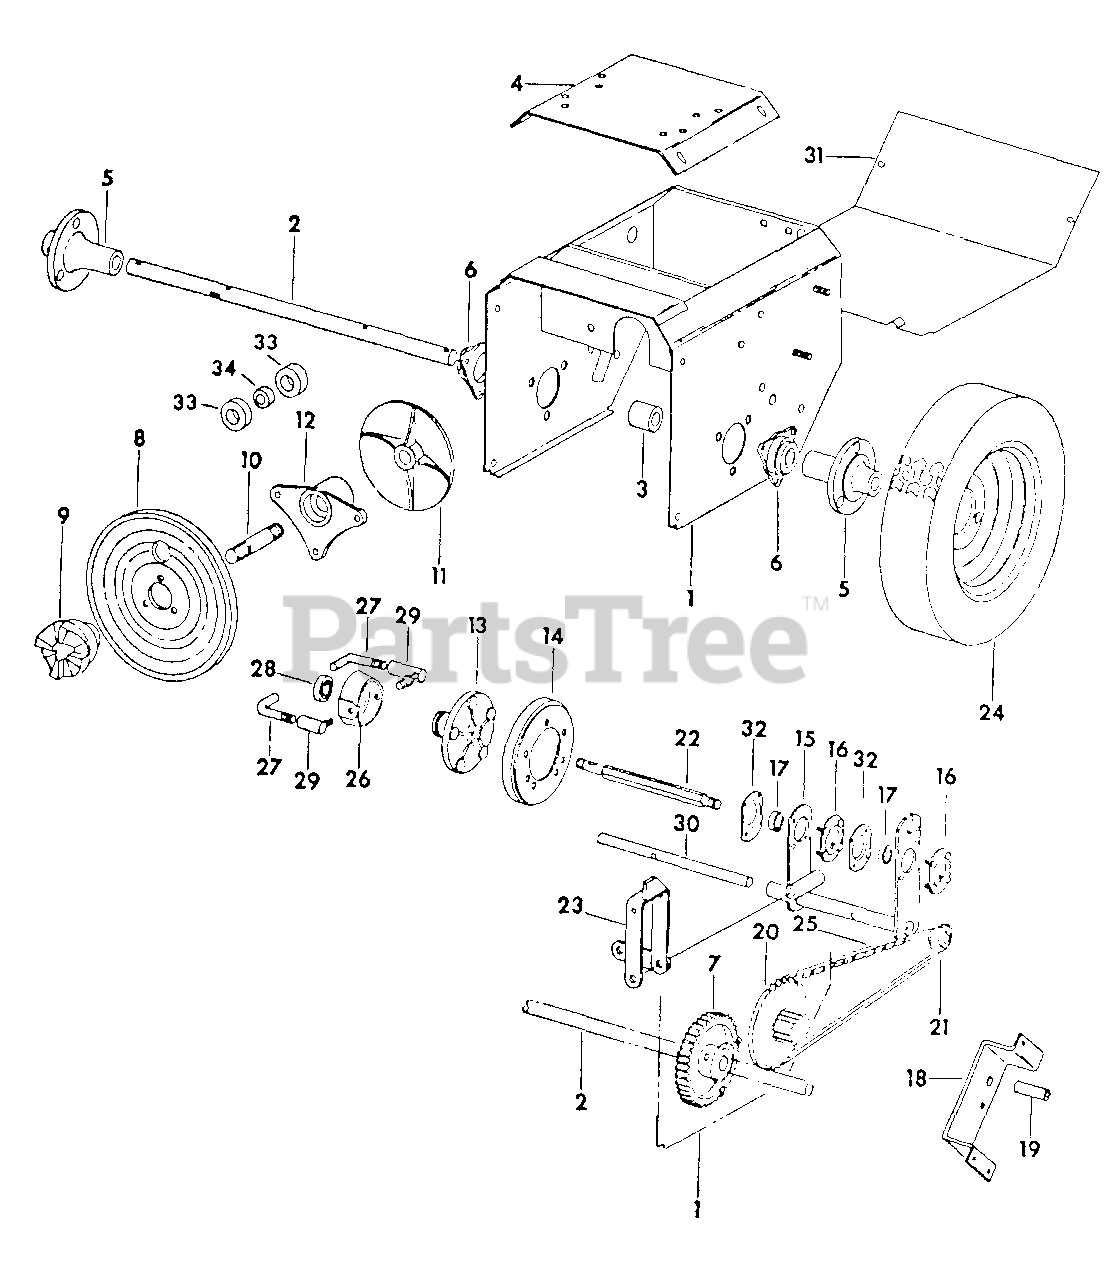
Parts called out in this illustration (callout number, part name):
1	HOUSING, MAIN DRIVE
2	AXLE
3	SPACER, AXLE
5	HUB , WHEEL
5	BRACKET, WHEEL MOUNTING
6	BEARING, FLANGE AXLE
6	FLANGE, AXLE BEARING
7	GEAR, SPUR - 40 TEETH
10	SHAFT, DRIVEN
12	HOUSING, BEARING
13	HUB, DRIVEN DISC
14	WHEEL, FRICTION
15	BRACKET, DRIVE
16	RETAINER, BRG
17	BEARING, BALL
18	BRACKET, TRANSFER
20	SPROCKET, SPUR GEAR
21	SPROCKET - 9 TEETH
23	BRACKET, SHIFTING
24	WHEEL W/TIRE ASSY
25	CHAIN, ROLLER
28	BEARING, BALL
29	JOINT, 1/4-28 BALL
30	SHAFT, PIVOT
31	PLATE, BOTTOM GUARD
32	RETAINER, BEARING
33	BEARING, HOUSING BALL
34	SPACER, BEARING
IH-102581	SCREW, 5/16-18 X 3/8 HDLS HEX-SOC-HD CUP-PT SET
